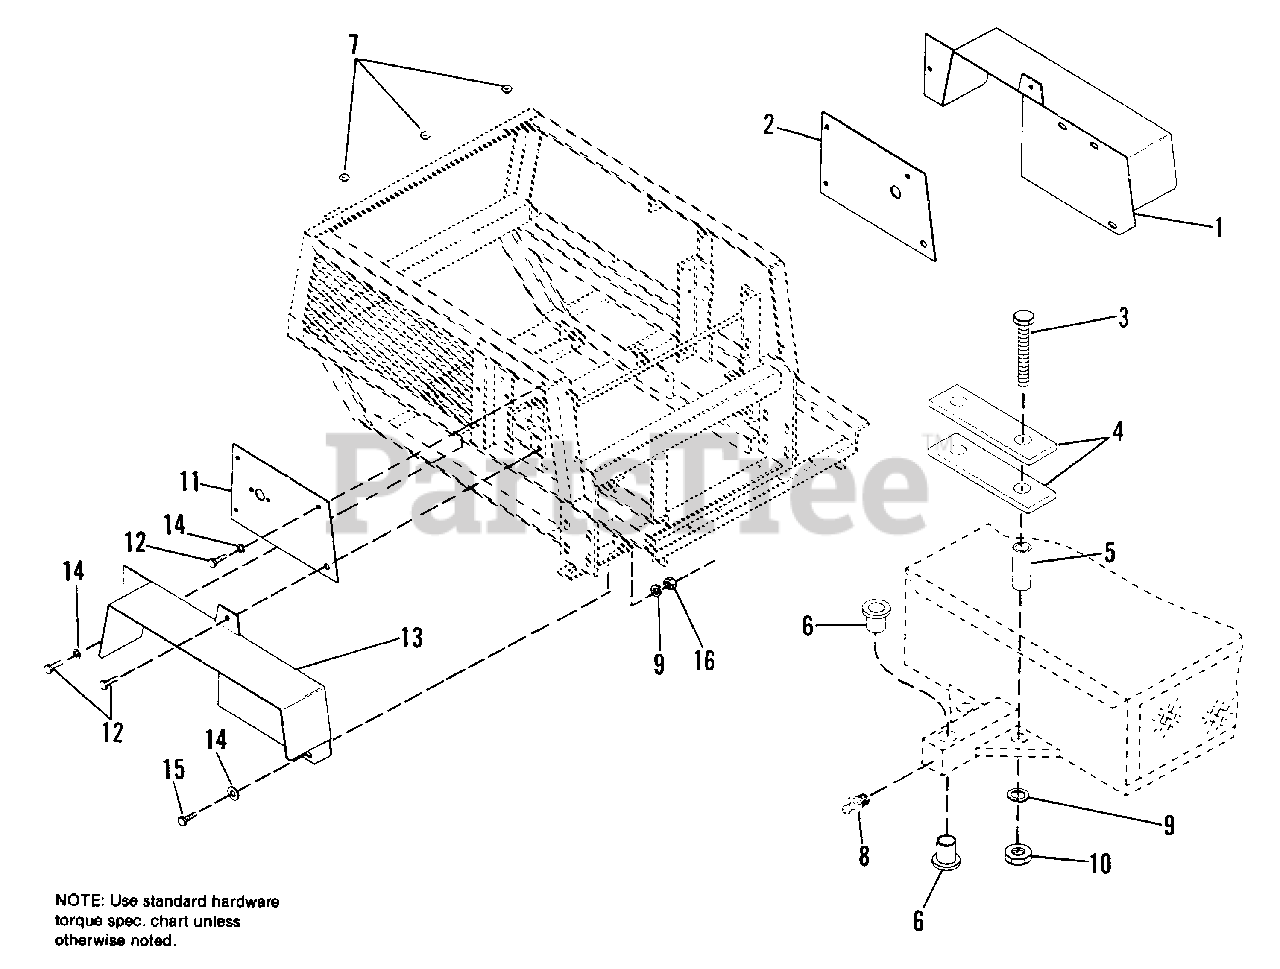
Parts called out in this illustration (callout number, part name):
1	FENDER ASSY., L.H.
2	SIDE, L.H.
3	CAPSCREW, Hex, 7/16-14 x 4-1/2
3	CAPSCREW, Hex, 7/16-14 x 5
3	CAPSCREW, Hex, 7/16-14 x 5-1/2
4	PLATE, Weight
5	TUBE, Spacer
6	BUSHING, Flanged
7	BUMPER, Rubber
8	FITTING, Grease
9	LOCKWASHER, Spring, 5/16
10	NUT, Hex, 7/16-14
11	SIDE, R.H.
12	SCREW, Taptite, 1/4-20 x 5/8
13	FENDER ASSY., R.H.
14	WASHER, Plain
15	CAPSCREW, Hex, 5/16-18 x 3/4
16	NUT, Hex, 5/16-18
